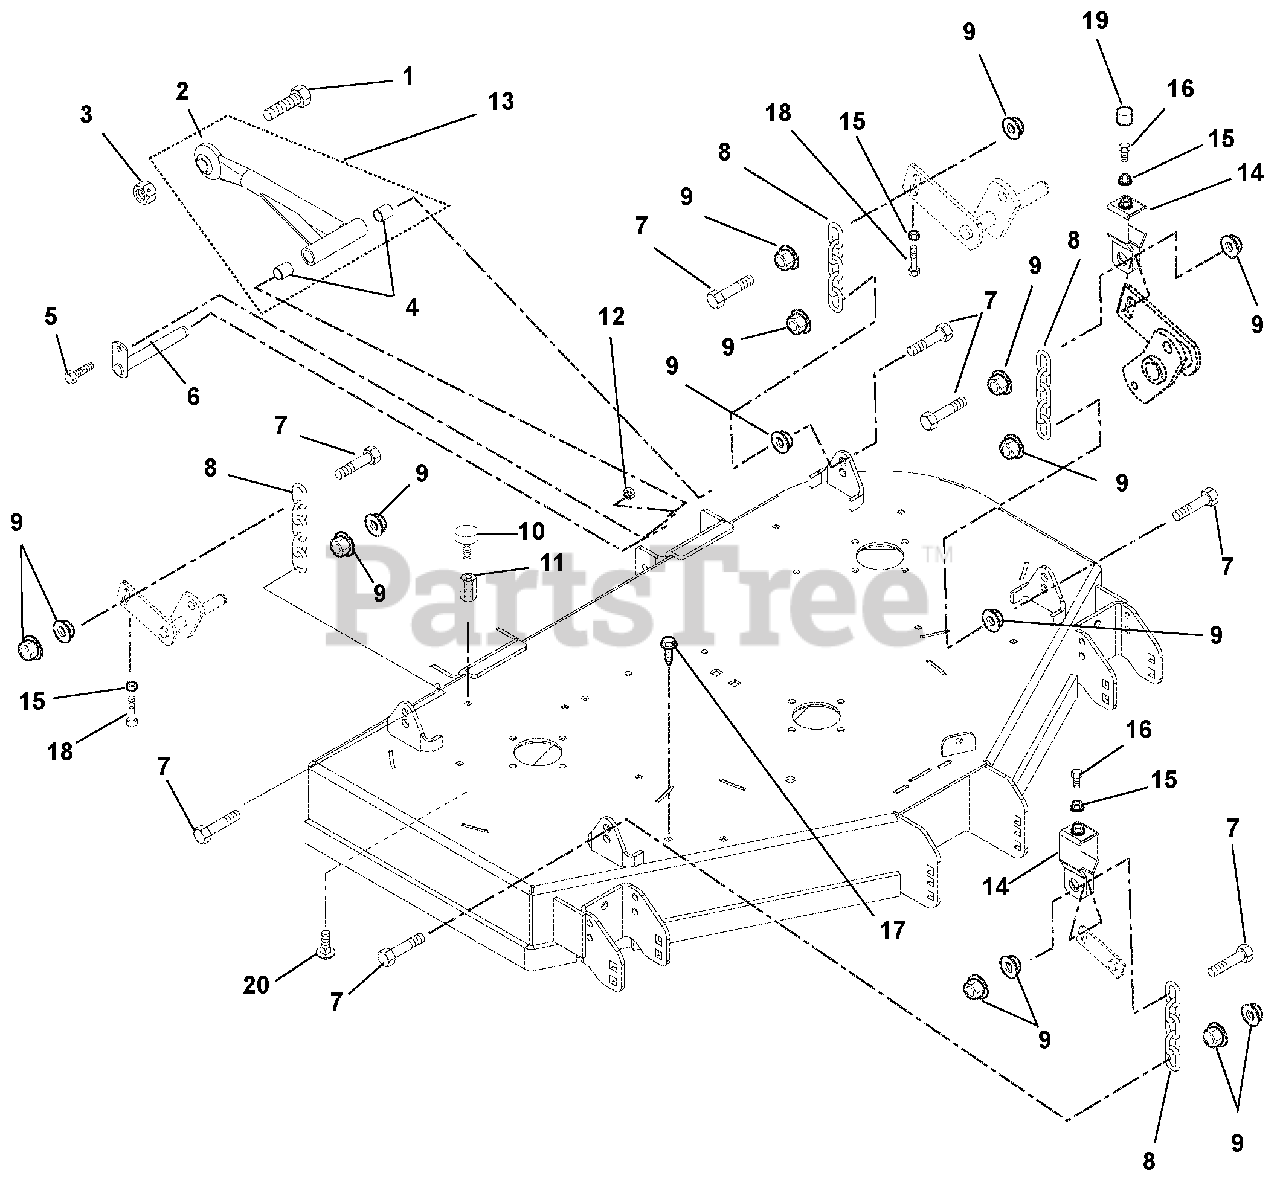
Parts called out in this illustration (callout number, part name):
1	Bolt, Hex .875-9 x 2.75 Grade 5
2	Mower Mounting Arm Weldment
3	Nut, Locking Center .875-9
4	Bearing, .75 x .875 x 1.00
5	Bolt, Hex .38-16 x 1.00
6	Weldment, Mower Mounting Pin
7	Bolt, Hex M12-1.75 x 50 Grade 5
8	Chain, Link
9	Nut, Spin Lock Flange M12-1.75
10	Bumper, Rubber
11	Nut, Coupling, .31-18 x 3.00
12	Nut, .38-16 Nyloc Flange
13	Assembly, Mower Mounting Arm (Includes items 2 and 4)
14	Bracket, Deck Leveling
15	Nut, Jam .312-18
16	Bolt, Hex .31-18 x 2.00 Full Thread
17	Screw, Tapping .38-16 x .50 Hex Washer Head Thread
18	Bolt, Hex .312-18 x 1.50 Grade 5
19	Cap, Vinyl .50 ID x 1.50 LG x .055
20	Bolt, Round Head Square Neck, .31-18 x .75 Loc-Tite®
